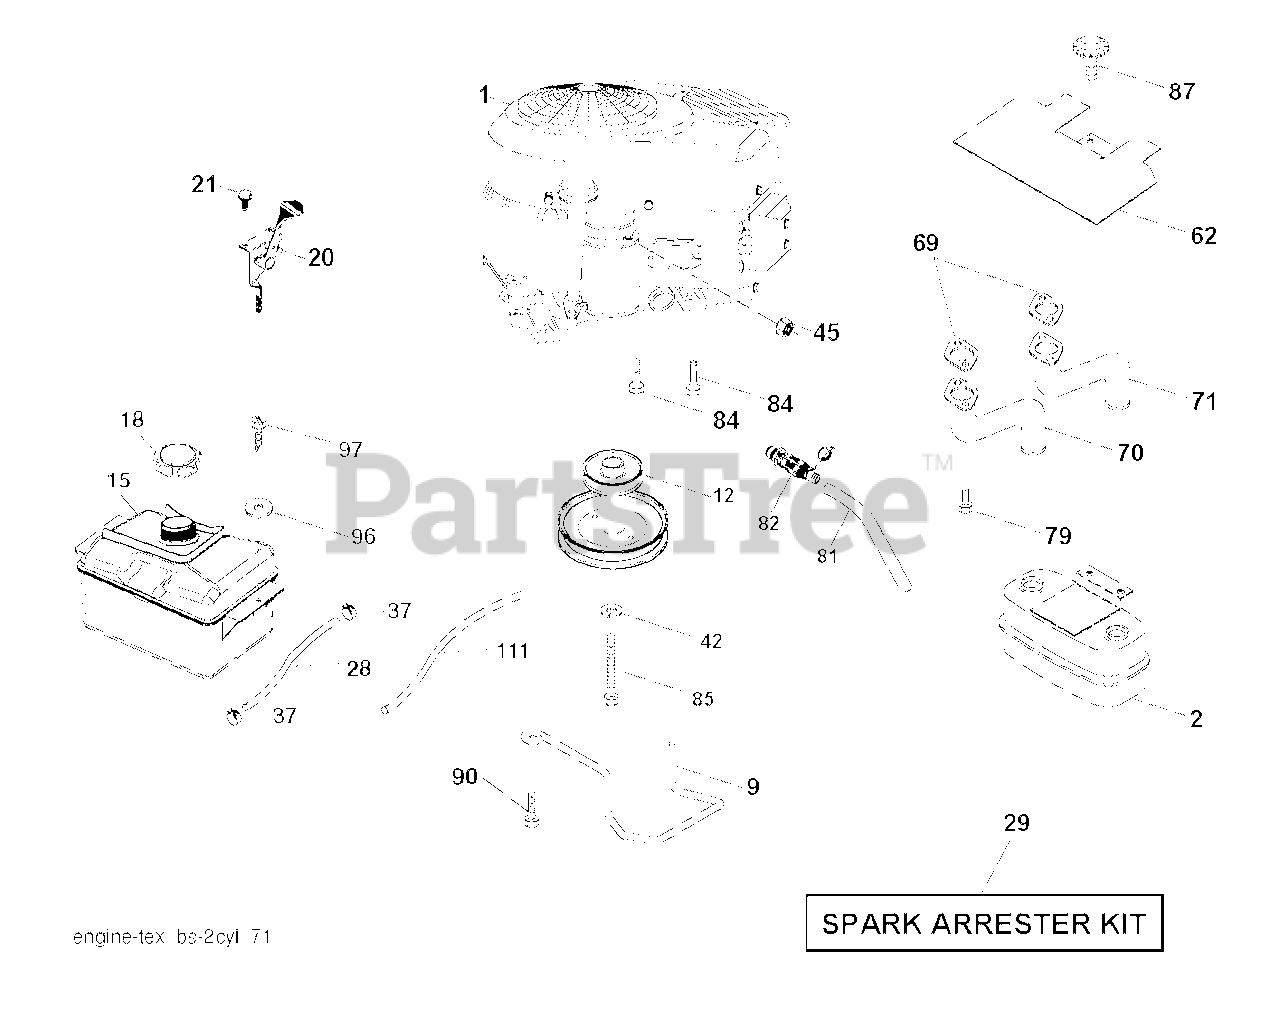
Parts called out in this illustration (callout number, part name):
2	MUFFLER.ASM.TWN.EXTNDED.DFLCTR
9	KEEPER.BELT.ENGINE.4.2
12	PULLY ENGINE
15	TANK.ASM.FRT.2.5 GAL.W/CAP.EPA
18	CAP.2.25'.VENTED.TETHER .EPA
20	CONTROL.TH/CK.COBRA.B&S.TWN.
21	SCREW.#10 X 0.750.BOS
28	LINE.FUEL.20"FRONT.EMI
29	KIT.SPARK ARRESTOR 794945 B&S
37	HOSE CLAMP
42	LOCKWASHER
45	NUT
62	SHIELD.HEAT.MUFFLER
69	GASKET.MUFFLER
70	RP.EXHAUST.TUBE.LH.BS/TWIN
71	EXHAUST.TUBE.RH.BS/TWIN
79	SCREW.SOCKET.HEAD.5/16-18
81	TUBE, DRAIN OIL ASM.
82	VALUE.OIL.DRAIN
84	SCREW.3/8-16
85	BOLT HEX 7/16-20X4-1/4"
87	BOLT, 5/16-18 X 1 3/4
90	SCREW 3/8-16X1
97	SCREW HEXWSHR 1/4-20X3/4
111	RP PURGE LINE
